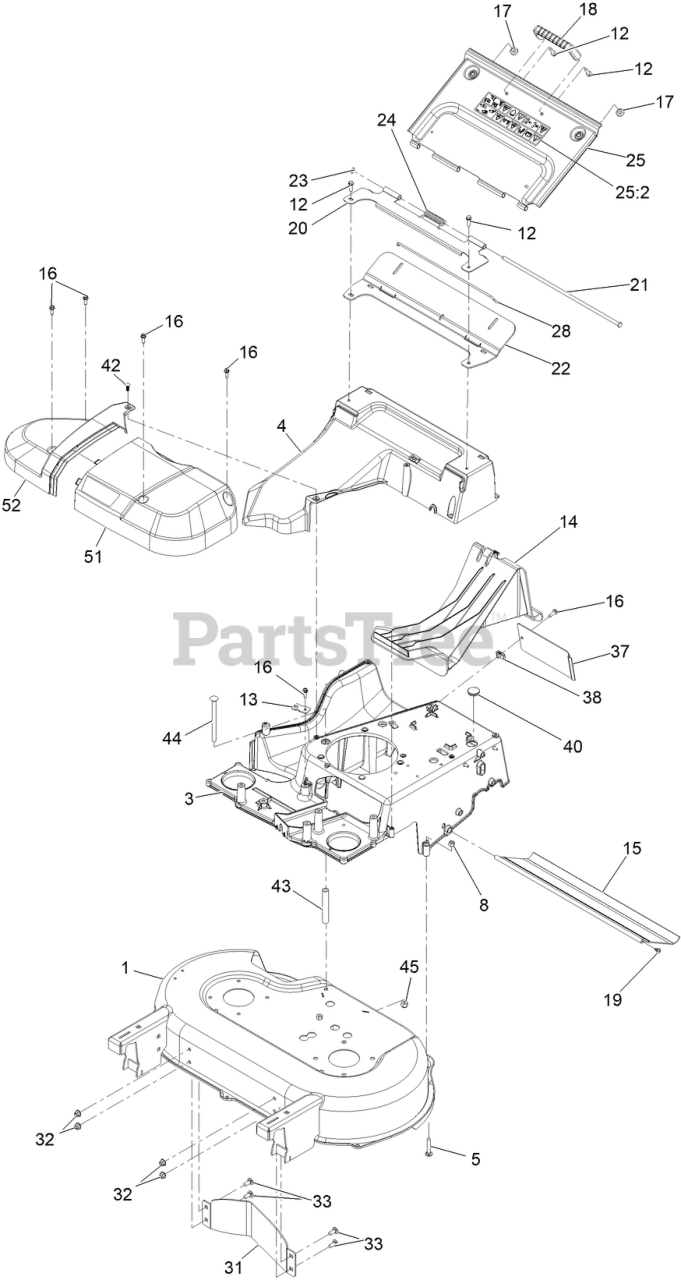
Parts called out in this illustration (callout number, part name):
1	Deck-30In
5	BOLT-CAR
8	NUT-LOCK, NI
12	SCREW-HWH
13	BRACKET-CABLE, TRACTION
14	PLUG-MULCH
15	SHIELD-TRAILING
16	SCREW-HWHTF
18	HANDLE-DOOR
19	SCREW-PTH
20	Weld-Tank Mount
21	PIN-HINGE
22	SEAL-DOOR
23	RING-RETAINING
24	SPRING-TORSION, COVER
25	REAR DOOR ASM
25:2	DECAL-WARNING
28	CLIP-SEAL
31	BAFFLE-CONTROL
32	NUT-HF, NI
33	SCREW-CARR
37	Cover-Frame
40	PLUG-BUTTON
42	Clip-Xmas Tree
44	BOLT-CARR
45	NUT-HEX
51	Cover-Belt, LH
52	Cover-Belt, RH
